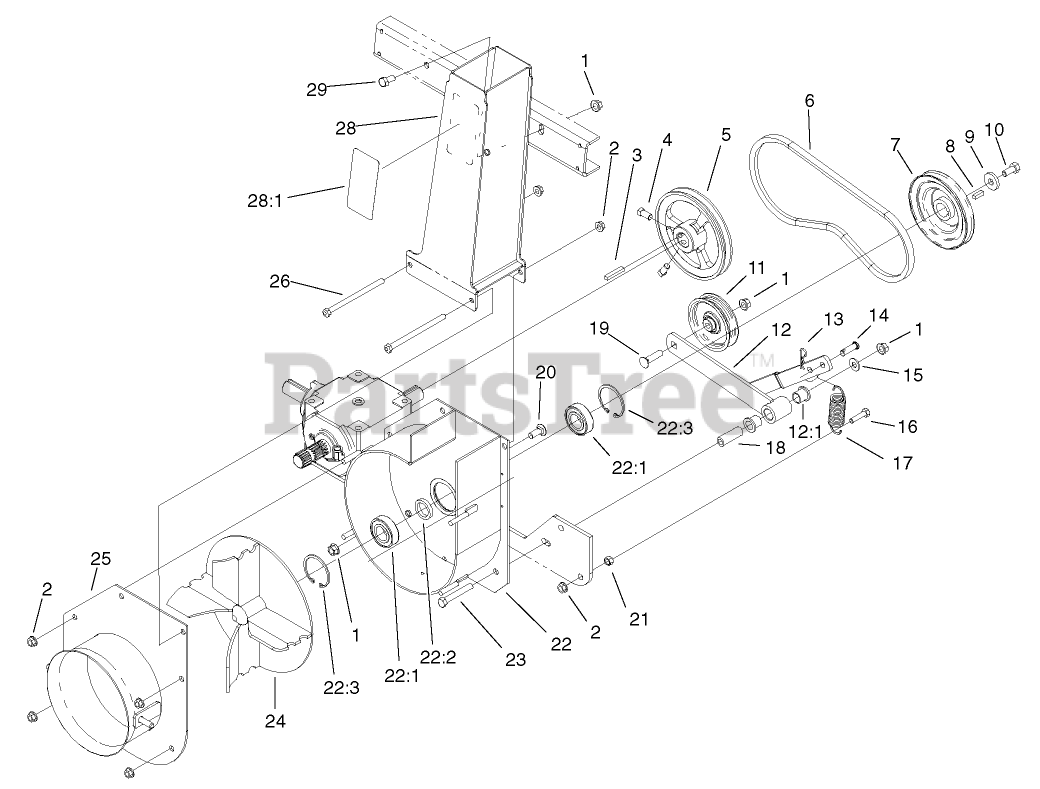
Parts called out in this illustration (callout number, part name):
1	NUT-HF
2	NUT-HF
3	KEY-SQUARE
4	SCREW-SET, SQH
5	PULLEY-GEARBOX
6	V-BELT
7	Pulley
8	KEY-SQUARE
9	WASHER-THRUST, PLAIN
10	SCREW-HH
11	PULLEY-IDLER
12	IDLER ARM ASM
12:1	BUSHING-FLANGE
13	PIN-HAIR
14	PIN-CLEVIS
15	WASHER-FLAT
16	SCREW-HH
17	SPRING-EXTENSION
18	SPACER
19	SCREW-CARR
20	BOLT-CARR
21	NUT-HEX
22	BLOWER HOUSING ASM
22:1	BEARING-BALL
22:2	SPACER-BEARING
22:3	RING-SNAP
23	SCREW-HH
24	IMPELLER ASM
25	COVER ASM
26	SCREW-HH
28	Impeller Chute ASM
28:1	DECAL-DANGER
29	SCREW-HH
